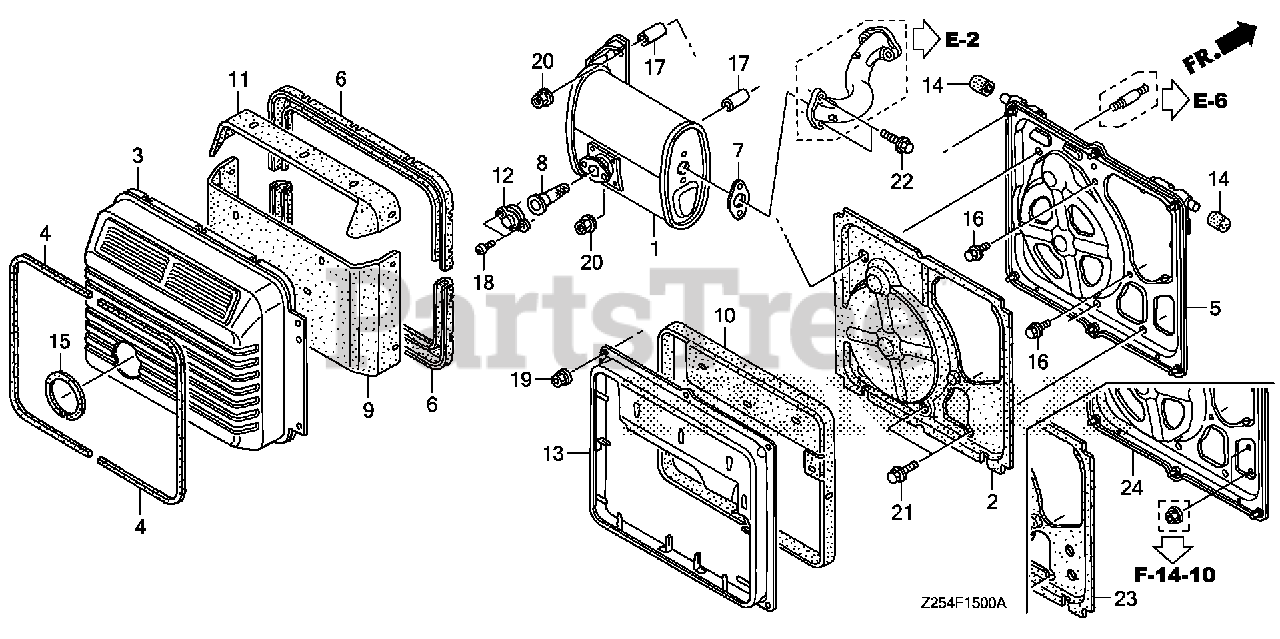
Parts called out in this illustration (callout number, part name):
2	SEPARATOR, MUFFLER (INNER)
3	PROTECTOR, MUFFLER (OUTER) *NH105* (MAT BLACK)
4	SEAL (10X5X785)
5	PROTECTOR, MUFFLER (INNER)
6	SEAL, MUFFLER PROTECTOR
7	GASKET, EX. PIPE
8	ARRESTER, SPARK
9	INSULATOR, MUFFLER PROTECTOR (A)
10	INSULATOR, MUFFLER PROTECTOR (B)
11	INSULATOR, MUFFLER PROTECTOR (C)
12	PIPE, EX. TAIL
13	GUIDE, EX. AIR
14	RUBBER, STOPPER
15	SEAL (10X8X290)
16	BOLT, FLANGE (6X12) (CT200)
17	COLLAR, MUFFLER
18	SCREW, PAN (5X16)
19	NUT, FLANGE (6MM)
20	NUT, FLANGE (8MM)
21	BOLT, FLANGE (8X16) Use from Engine SN 1000016.
22	BOLT, FLANGE (8X25)
